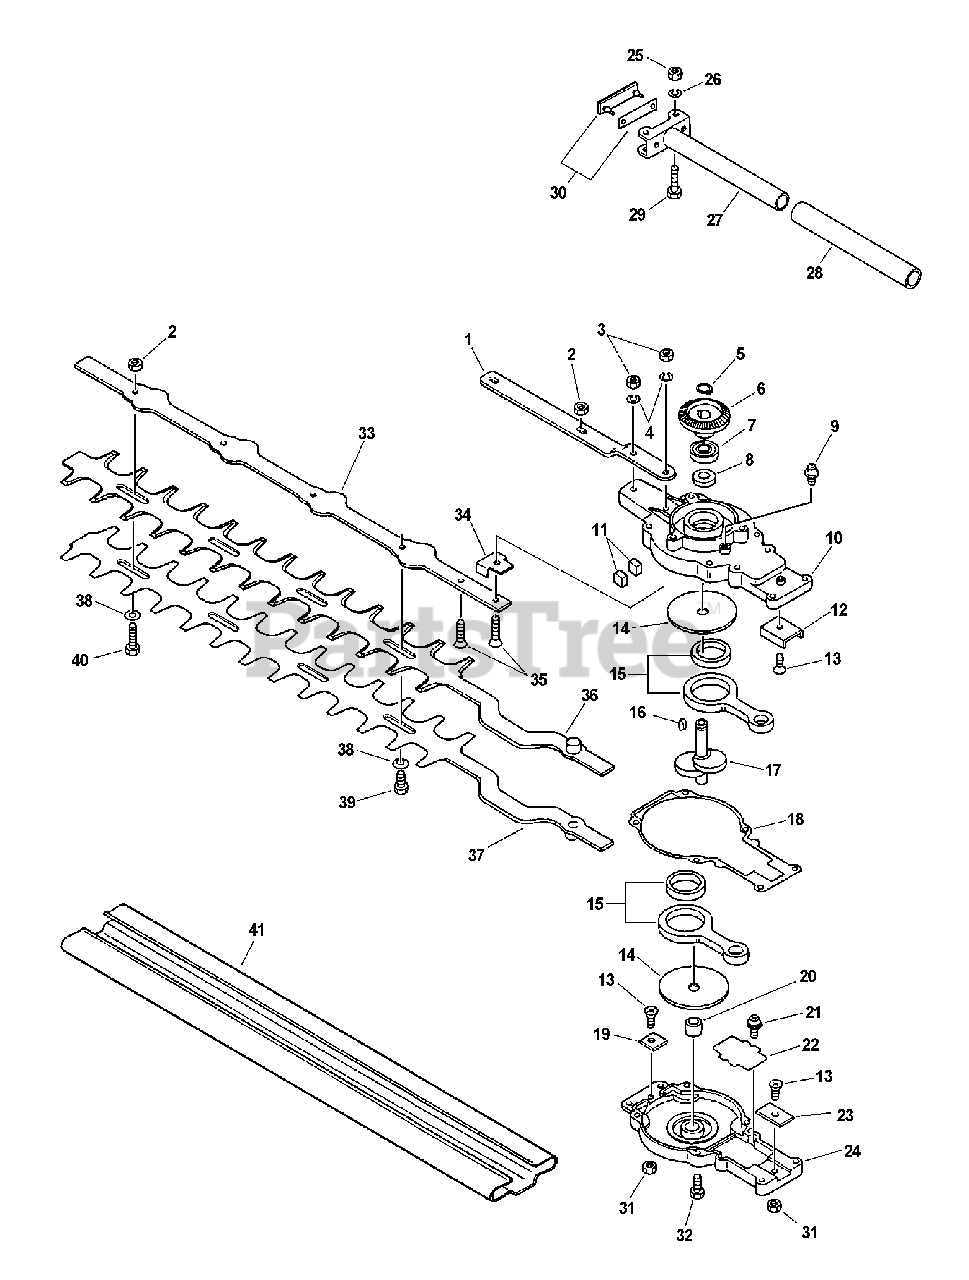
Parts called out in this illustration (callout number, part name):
1	SUPPORT, BLADE
2	LOCKNUT - 6
4	LOCKWASHER - 5
5	RING, RETAINING - 10
6	GEAR - SPUR
7	BEARING, BALL - 6000
8	SEAL, OIL
9	FITTING, GREASE
10	CASE, GEAR
11	SEAL, FELT
13	SCREW - 4X8
14	PLATE, SIDE
15	ROD, CONNECTING
18	GASKET, GEAR CASE
19	PLATE, GUIDE
20	BEARING, PLAIN
21	SCREW - 3X6
22	PLATE, SIDE
24	LID, GEAR CASE
26	LOCKWASHER - 5
28	GRIP, HANDLE
29	BOLT - 5X25
30	SPACER KIT
32	BOLT - 5X20
33	SUPPORT, BLADE
34	PLATE, ANGLE
35	SCREW - 5X20
36	BLADE - "TB" -- UPPER
37	BLADE - "BB" -- LOWER
38	WASHER - 6
39	BOLT - 6X22
41	COVER, BLADE
